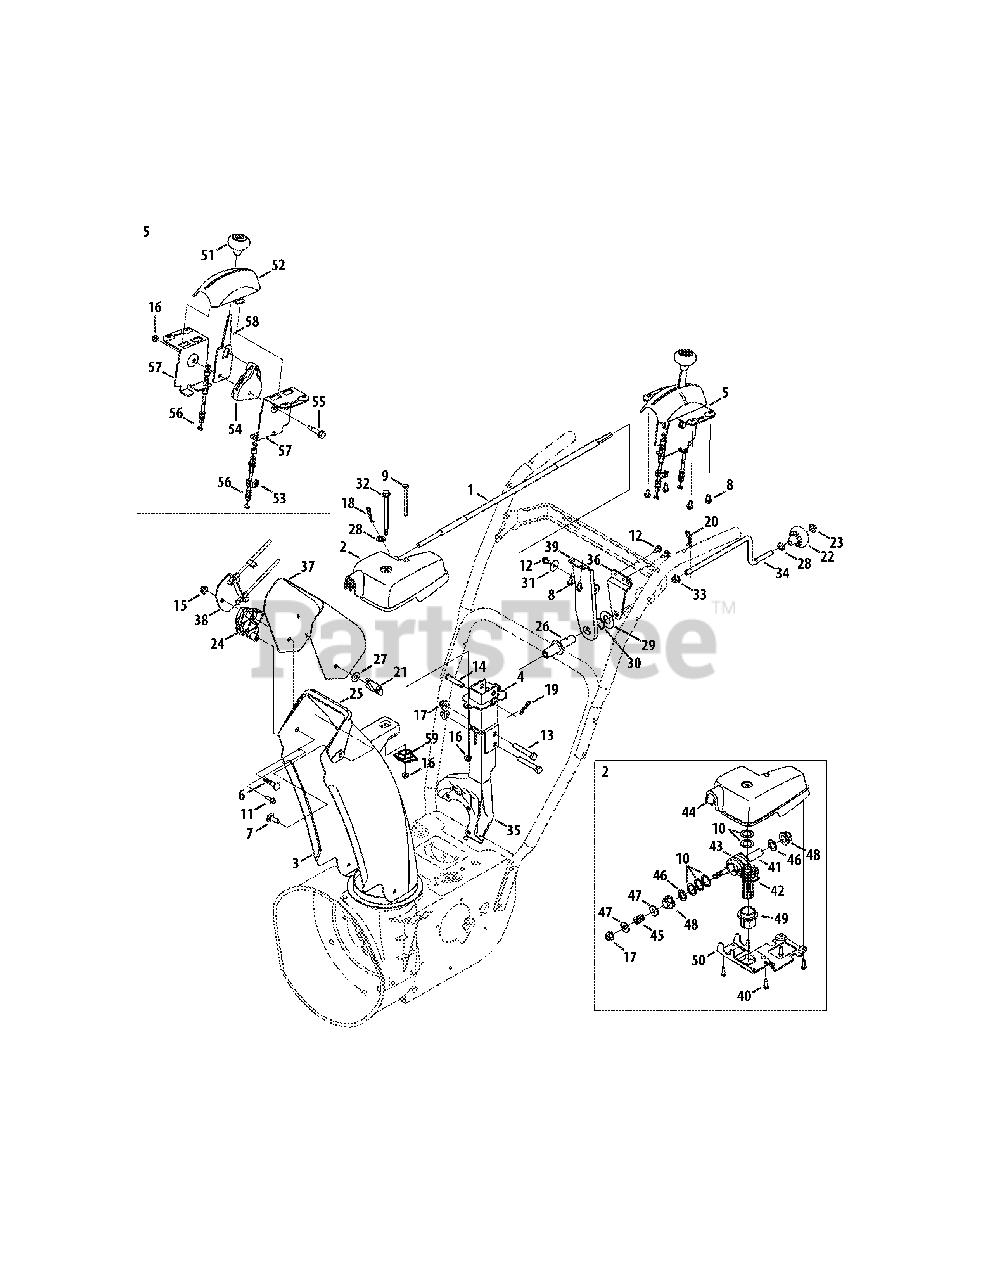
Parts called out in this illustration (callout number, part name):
1	Control Assembly
2	Chute Rotation Gearbox
3	Chute, Lower
4	Support Bracket Extension
5	Chute Control, 2-Way
6	Bolt, Carriage, 5/16-18 x 1.50
7	Bolt, Carriage, 5/16-18 x 1.00
8	Screw, HL, 1/4-15 x 0.50
9	Hex Head Screw, 1/4-20 x 3.00
10	Shim Washer, .632 x 1.00 x .010
11	Screw, HL, 1/4-15 x 0.750
12	Hex Washer Screw, 1/4-20 x .625
13	Hex Cap Screw, 3/8-16 x 2.25
14	Clevis Pin, 3/8 x 1.87
15	Nut, Flangelock, 5/16-18
16	Nut, Flangelock, 1/4-20
17	Flange Lock Nut, 3/8-16
18	Internal Cotter Pin
19	Bow-Tie Cotter Pin
20	Internal Cotter Pin
21	Wing Knob, 5/16-18
23	Push Cap, 3/8
24	Chute Cable Guide
25	Chute Adapter
26	Chute Control Rod Coupling
27	Washer, Flat, .349 x .879
28	Flat Washer, .375 x .738 x .063
29	Flat Washer, .78 x 1.59 x .06
30	Washer, Wave, .785 x 1.0 x .012
31	Flat Washer, .265 x 1.00 x .030
32	Screw, Shoulder, .312 x 3.5 x 1/4-20
33	Plastic Bushing, .38
35	Chute Support Bracket
36	Support Rod Bracket
38	Cable bracket
39	Chute Control Support Bracket
40	Screw, 12-16 x .75
42	Gear Assembly
43	Worm
45	Compression Spring, .39 x .60 x .88
46	Flat Washer, .625 x 1.0 x .067
47	Flat Washer, .380 x .93 x .110
48	Hex Bearing
49	Flange Bearing
51	Shift Knob
52	Cover, Tilt Cover
53	Cable Clip
54	Chute Tilt Cable Guide
55	Screw, Shoulder, .31 x .995:1/4-20
56	Cable, Chute Tilt
57	Bracket, Mounting
59	Chute Gear Adapter
